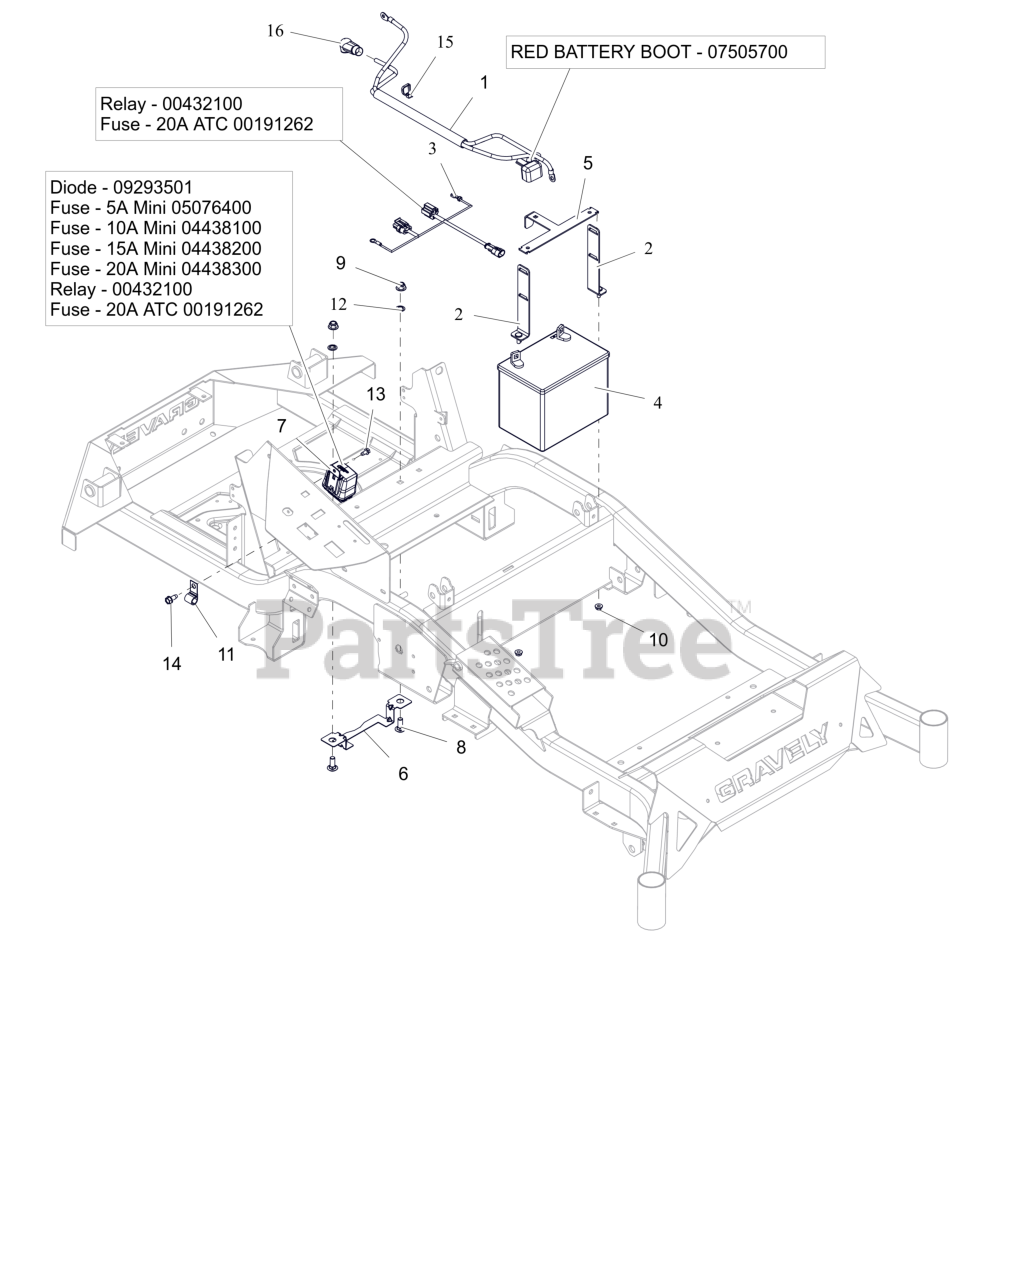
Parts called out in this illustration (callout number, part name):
1	HARNESS, BATTERY HD
1	INSULATOR
2	WMT,BATTERY MOUNT HOLD DOWN
3	HARNESS, STARTER ADAPTER
3	RELAY,SEALED W/DIODE
4	BATTERY, 300 CCA 10U1L
5	BRKT, BATTERY TIE DOWN
6	GUARD, ELECTRICAL HARNESS
7	HARNESS, WIRE
7	DIODE, CONNECTOR SHELL
7	FUSE, 5 AMP MINI-ATC
7	FUSE,10 AMP MINI-ATC
7	FUSE,15 AMP MINI-ATC
7	FUSE,20 AMP MINI ATC
7	RELAY,SEALED W/DIODE
7	FUSE, 20 AMP BLADE S/O
8	BLT, RHSN .38-16X1.00 G5 ZCC
9	NUT,NYL-FLG .38-16 GF ZCC
10	NUT-LK-TOP-FLG .250-20 GF ZCC
12	NUT-PUSH .38 DIA. PAL ZINC
13	SCR-TAP .25-20X.50 HWH ZCC
14	SCR,TAP .312-18X.75 HWH TR ZCC
15	CABLE TIE W/ TREE (.25 HOLE)
16	BOOT, .65ID POS
